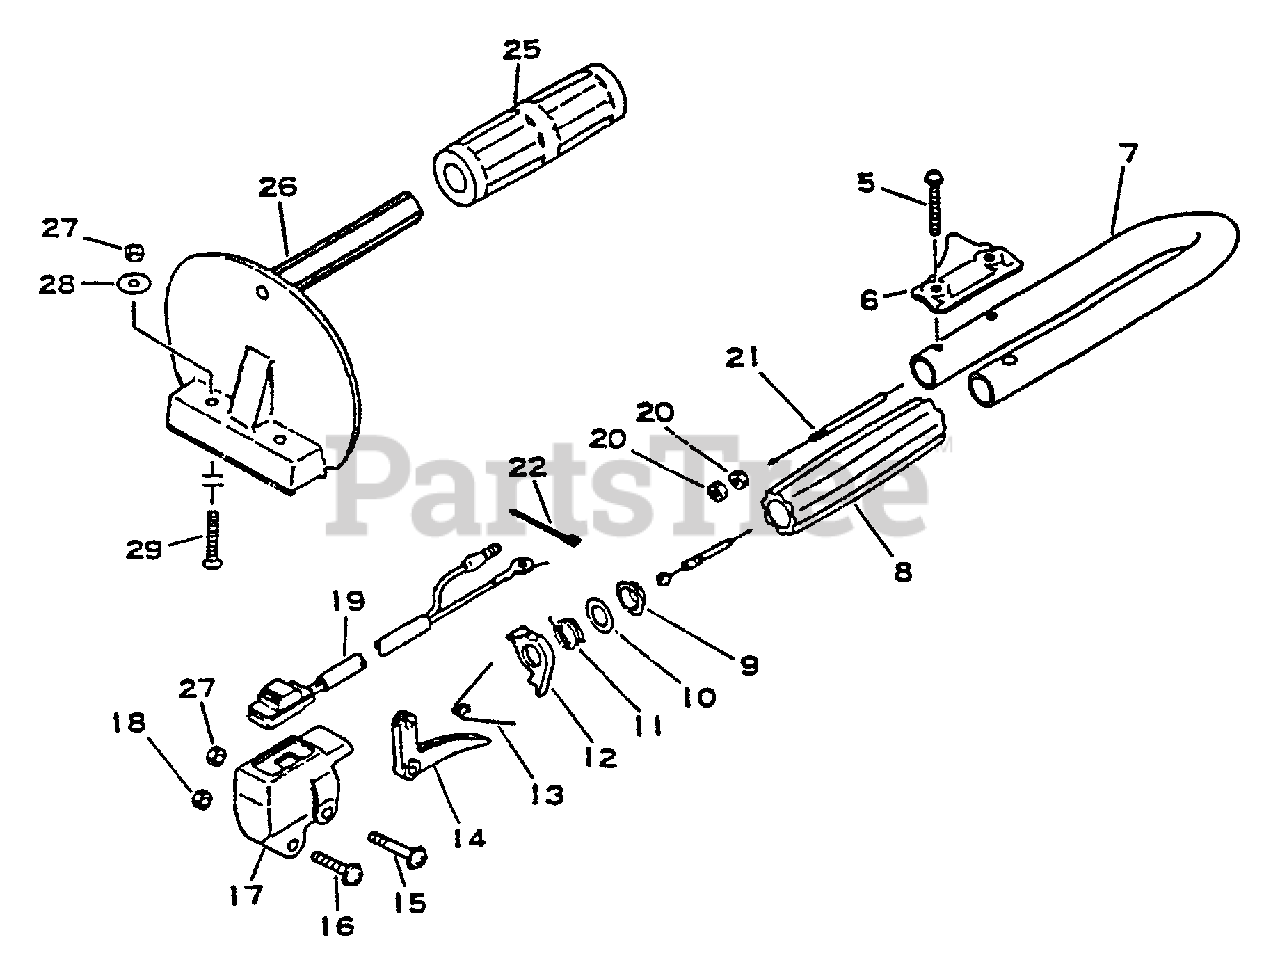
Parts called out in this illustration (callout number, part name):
5	SCREW 5×35
6	BRACKET, HANDLE
7	HANDLE - REAR
10	SPACER
11	SPRING, THROTTLE LOCK
12	LOCKOUT, TRIGGER
14	TRIGGER, THROTTLE
16	SCREW 5×28
17	BRACKET, THROTTLE
18	NUT M5
19	IGNITION SWITCH ASSY
21	CABLE, THROTTLE
26	HANDLE, FRONT
27	LOCKNUT - 5
28	WASHER 5.5×18×1
29	SCREW 5×30
